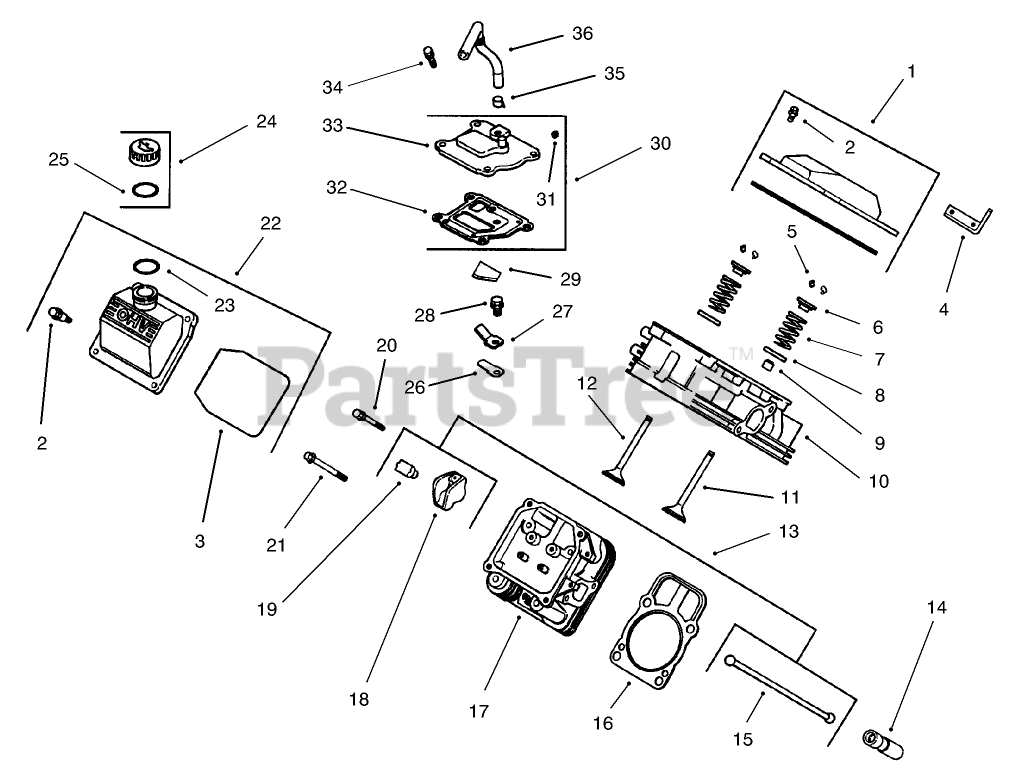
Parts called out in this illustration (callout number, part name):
1	Kit-Valve Cover (Incl. Ref. #2 3)
2	Screw-Shoulder
3	O-Ring
4	Strap-Lifting
5	Kit-Retainer
6	Cap-Valve Spring
7	Spring-Valve
8	Retainer-Spring
9	Seal-Valve Stem
10	Head Assembly (#1 Cylinder)
11	Valve-Intake
12	Valve-Exhaust
13	Kit-Valve Incl 1726-27
14	Lifter-Valve
15	Rod-Push
16	Gasket-Cylinder Head
17	Head-Assembly (#2 Cylinder)
18	Arm-Rocker
19	Pivot-Arm, Rocker
20	Screw
21	Screw
22	Kit-Valve Cover (Incl. Ref. #2-4)
23	ORing
24	Kit-Oil Fill Cap (Incl. Ref. #7)
25	ORing
26	Reed
27	Retainer-Reed
28	Screw
29	Filter-Breather
30	Kit,-Breather
31	Plug
32	Gasket-Breather
33	Cover-Breather
34	Screw
35	Clamp
36	Hose-Breather
